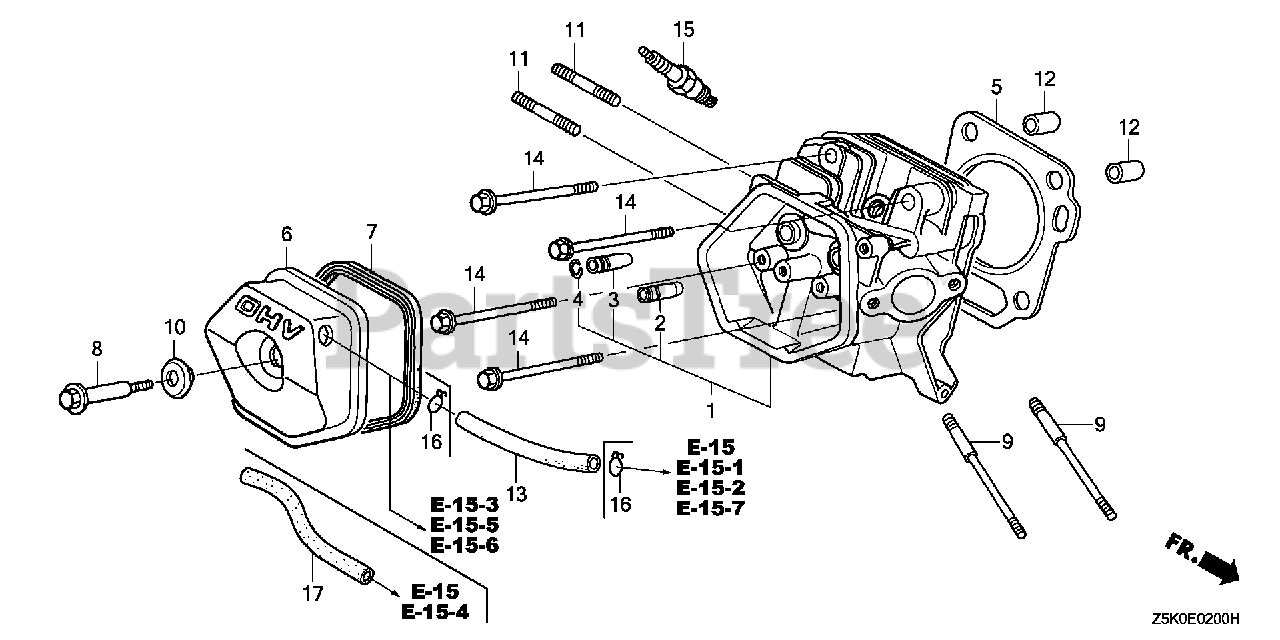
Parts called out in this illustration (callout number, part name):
1	CYLINDER HEAD
2	GUIDE, VALVE (OVER SIZE)
3	GUIDE, EX. VALVE (OVER SIZE)
4	CLIP, VALVE GUIDE
5	GASKET, CYLINDER HEAD (THAI LEAKLESS)
6	COVER, HEAD
7	GASKET, HEAD COVER
8	BOLT, HEAD COVER
9	BOLT, STUD (8X123)
10	WASHER, HEAD COVER
11	BOLT, STUD (8X32)
12	PIN, DOWEL (12X20)
13	BULK HOSE, VACUUM (11X1000) (11X100)
14	BOLT, FLANGE (10X80)
15	SPARK PLUG (BPR6ES) (NGK)
